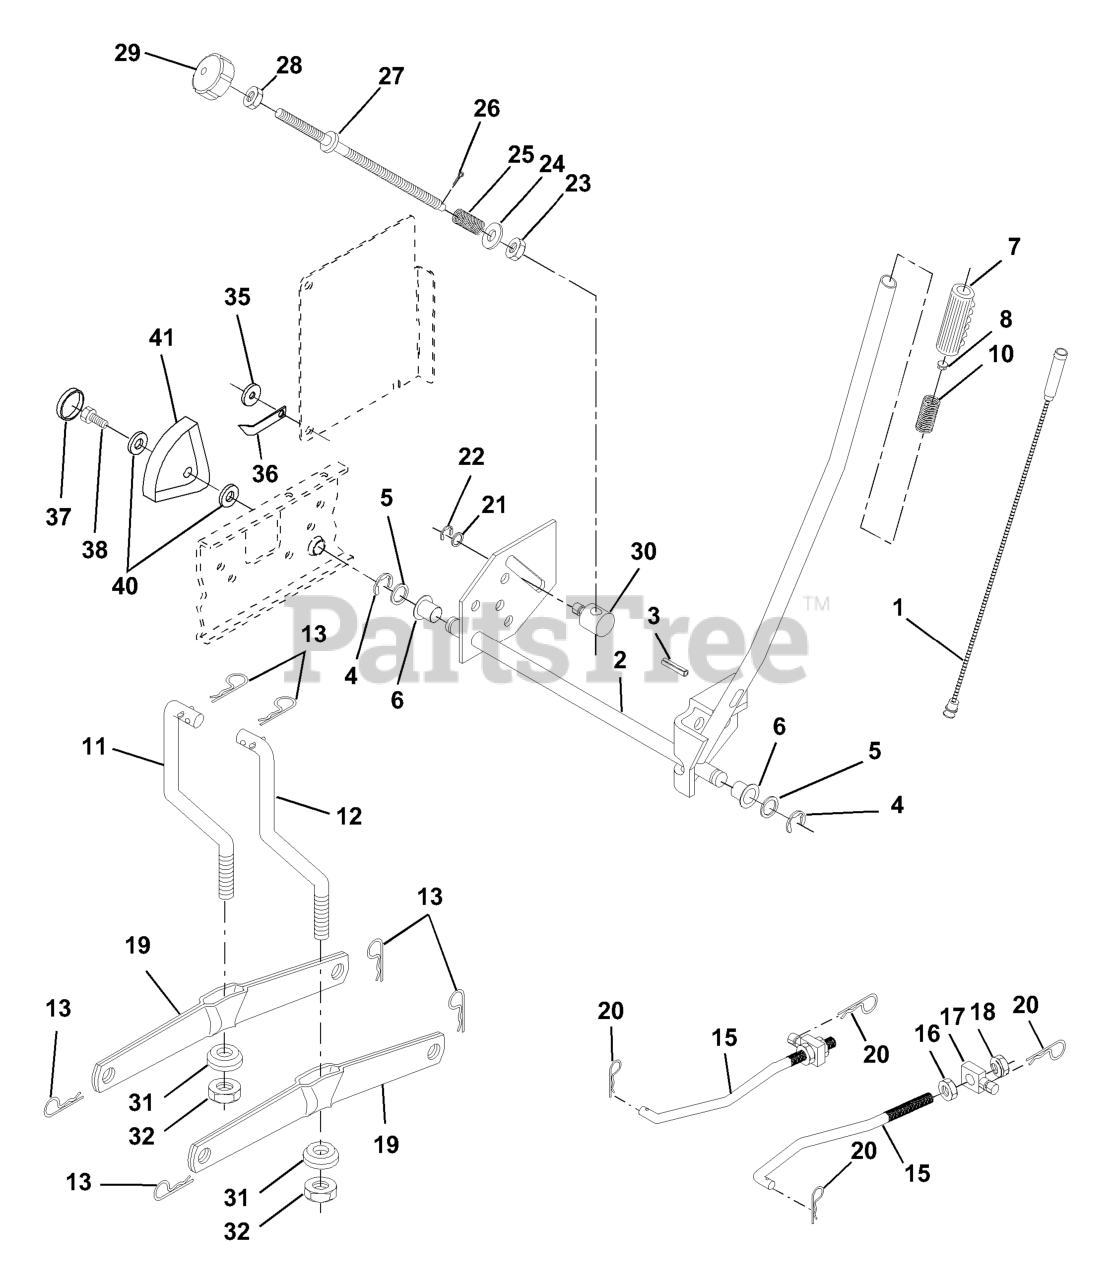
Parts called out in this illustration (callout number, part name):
1	WIRE ASM INNER
2	SHAFT ASM LIFT RH
3	PIN GROOVE
4	RETAINING RING LT
6	BEARING.NYLON
7	GRIP HANDLE
8	PLUNGER BUT KIT
10	SPRING, COMP T
11	LINK LIFT LH
12	LINK LIFT RH
13	RETAINER-SPRNG RB
15	FRONT LINK
16	NUT.HEX.JAM.1/2-13
17	TRUNION
18	NUT.LK.W/WSH.1/2.
19	ARM.REAR.SUSPENSION
20	SPRING RETAINER
21	Washer 15/32 X 3/4 X 16 Ga
22	Ring Klip #t5304-37
25	SPRING**
26	COTTER PIN
27	ROD LIFT LT
28	NUT
29	KNOB INF 3/8-16
30	TRUNION LT
31	BEARING PIVOT
36	POINTER HGT
38	SCREW.THDROL.5/16-18X3/4.TTY
41	HEIGHT INDICATOR
